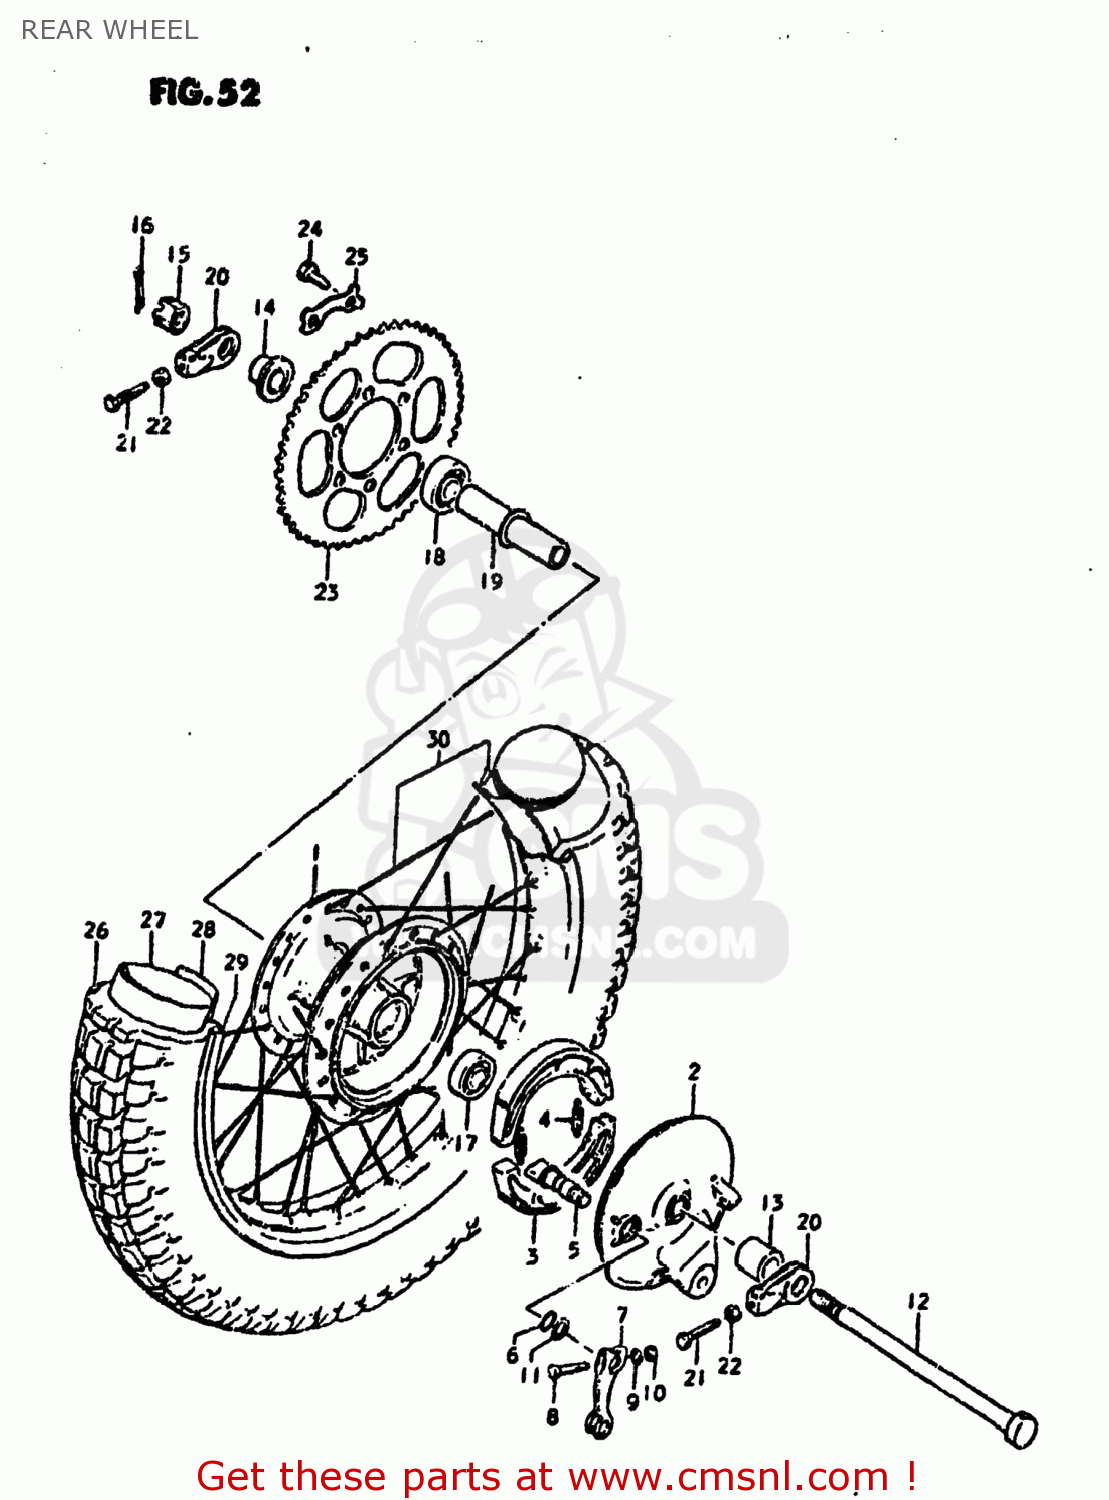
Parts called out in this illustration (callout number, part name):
1	HUB,REAR WHEEL
2	PANEL,RR BRAKE ANCHOR
3	SHOE,BRAKE
4	SPRING(L:34)
5	CAM,FRONT BRAKE
6	O-RING (D:2.4 ID:13.8)
7	LEVER,RR BRAKE CAM
8	BOLT 6X40
9	WASHER
10	NUT
11	WASHER (14.5X22X1.6)
12	AXLE,REAR
13	SPACER(15.2X22X26)
14	SPACER,RR AXLE,L
15	NUT
16	COTTER PIN
17	BEARING
18	BEARING
19	SPACER,RR WHEEL HUB BEARING
20	ADJUSTER,CHAIN,R
21	BOLT
22	NUT
23	SPROCKET,REAR
24	BOLT(8X30)
25	WASHER
26	TIRE
27	TUBE,INNER
28	PROTECTOR,INNER TUBE
29	RIM,RR WHEEL
30	SPOKE SET
